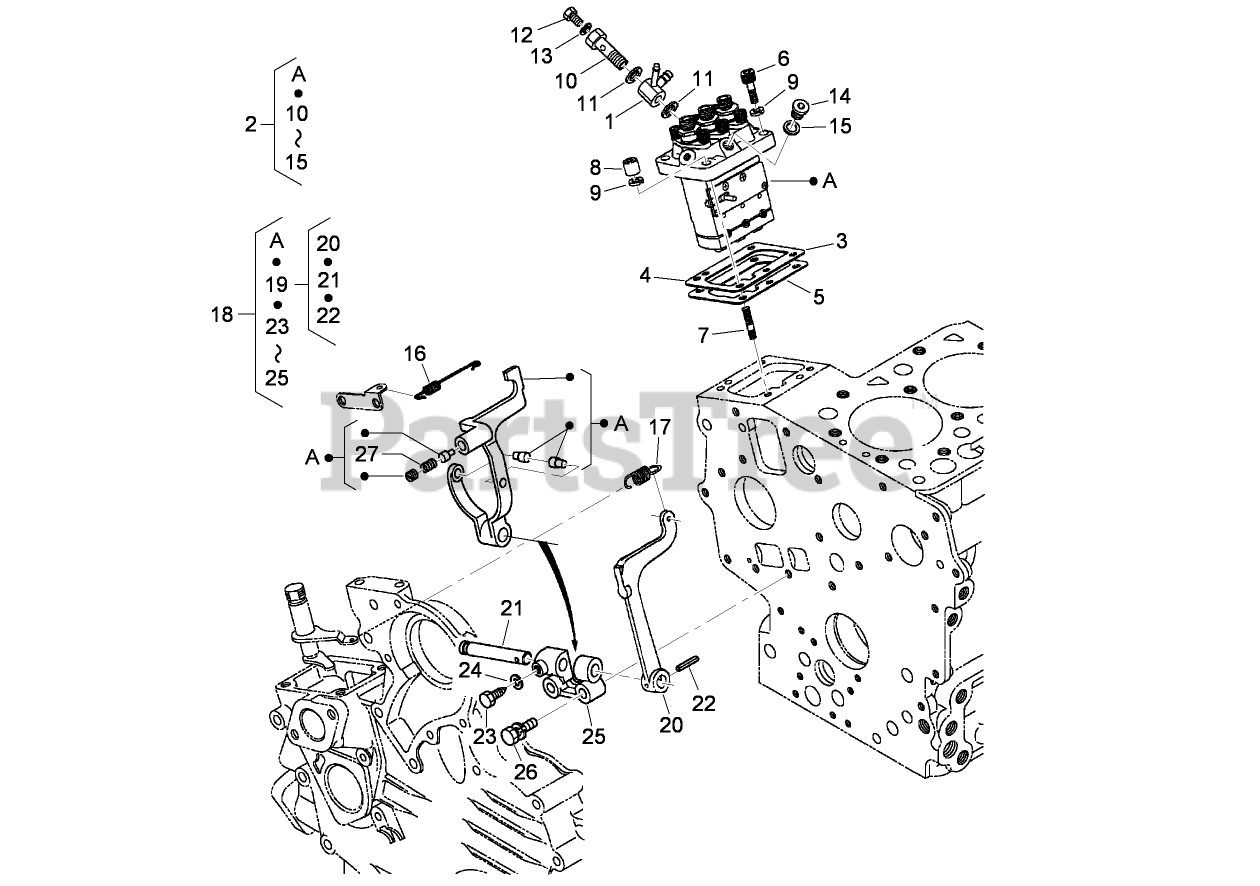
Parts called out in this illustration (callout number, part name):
2	INJECTION PUMP ASM
3	SHIM-INJECTION (0.20MM)
4	SHIM-INJECTION (0.25MM)
5	SHIM-INJECTION (0.30MM)
6	BOLT-HSH
8	NUT-CAP
9	WASHER-SPRING
10	SCREW-HOLLOW
11	GASKET
12	SCREW
13	GASKET
15	GASKET
16	SPRING-START
17	SPRING-GOVERNOR
18	FORK LEVER ASM
19	FORK LEVER ASM
20	LEVER-FORK
21	SHAFT-LEVER, FORK
22	PIN-SPRING
24	WASHER-SPRING
25	HOLDER-LEVER, FORK
27	SPRING
